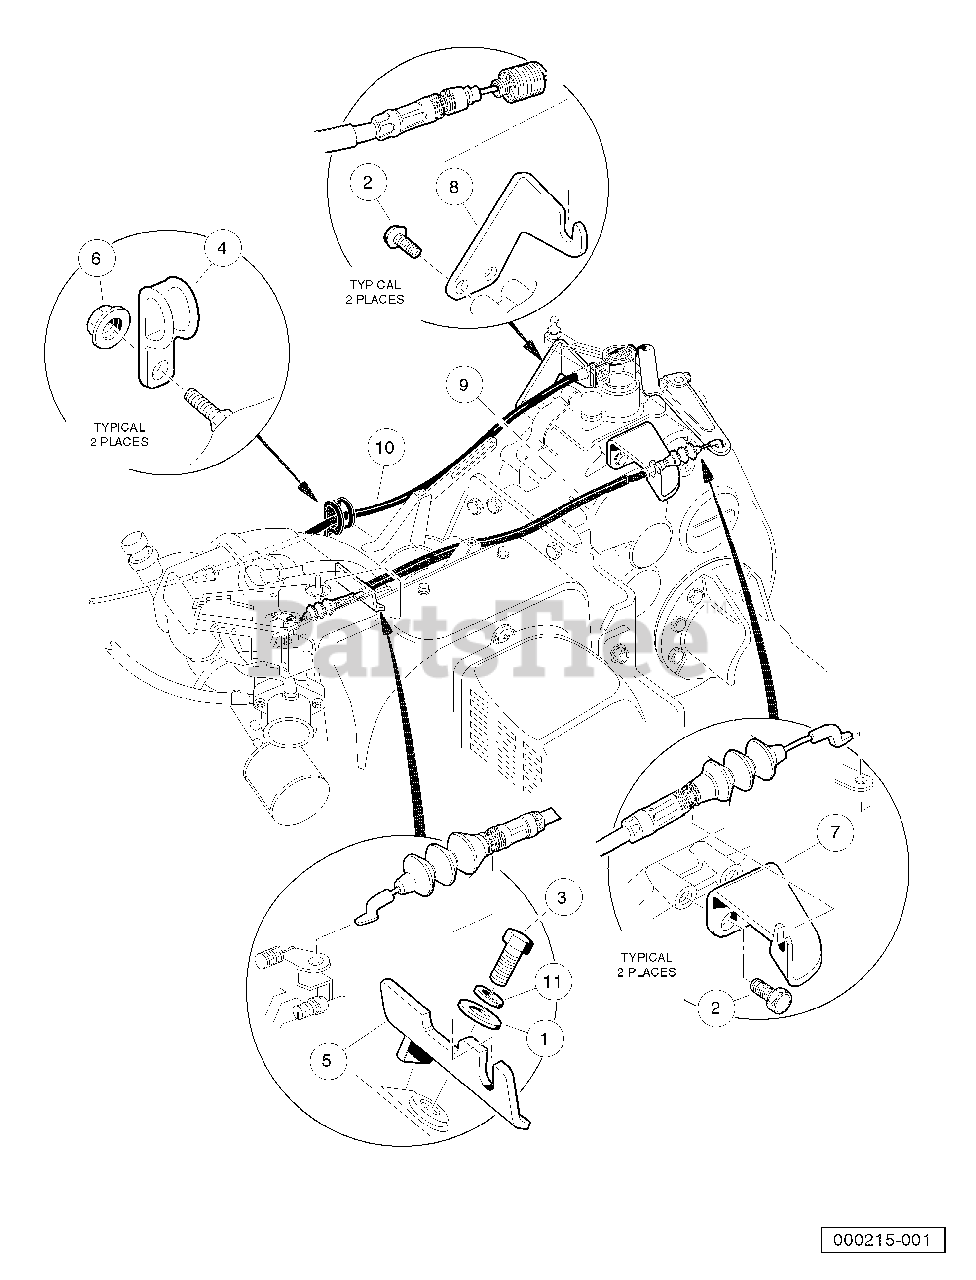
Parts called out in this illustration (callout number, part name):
1	Washer, 5/16 Flat
2	Screw, 1/4 X 0.625 Hex-Head
3	Screw, M8-125 X 22 Hex-Head
5	Bracket, Governor Cable Snap-In
7	Bracket, Rear Governor Cable Snap-In
8	Bracket, Rear Accelerator Cable Snap-In
9	Cable, Governor, Snap-In
10	Cable, Accelerator, Snap-In
11	Lockwasher, 5/16 Split
